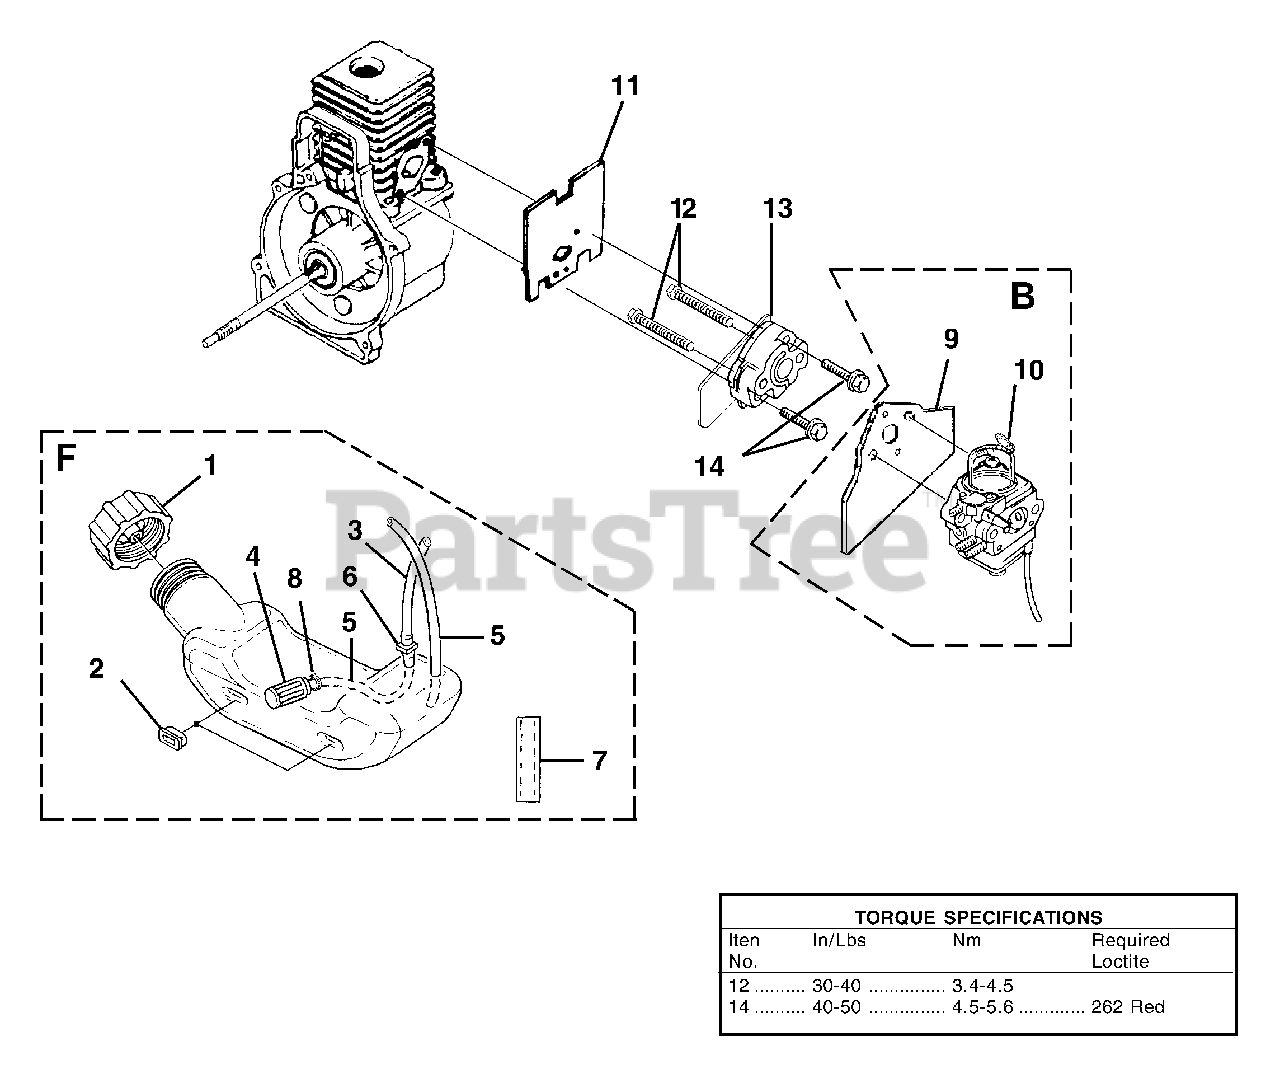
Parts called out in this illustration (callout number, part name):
1	FUEL CAP ( 1 5/8" Opening)
2	BUMPER-Rubber
3	TUBING-Rubber (5.5")
4	FUEL FILTER
5	TUBING-Rubber (6 1/4")
6	Fitting, Inlet
7	INSULATION-Tubing
8	CLAMP
9	GASKET-Carburetor
10	LEVER-Choke
11	GASKET-Heat Dam
12	CARB. BOLT
13	HEAT DAM
14	SCREW, SEMS (10-24 x 1.110)
F	FUEL TANK KIT
B	CARBURETOR KIT
